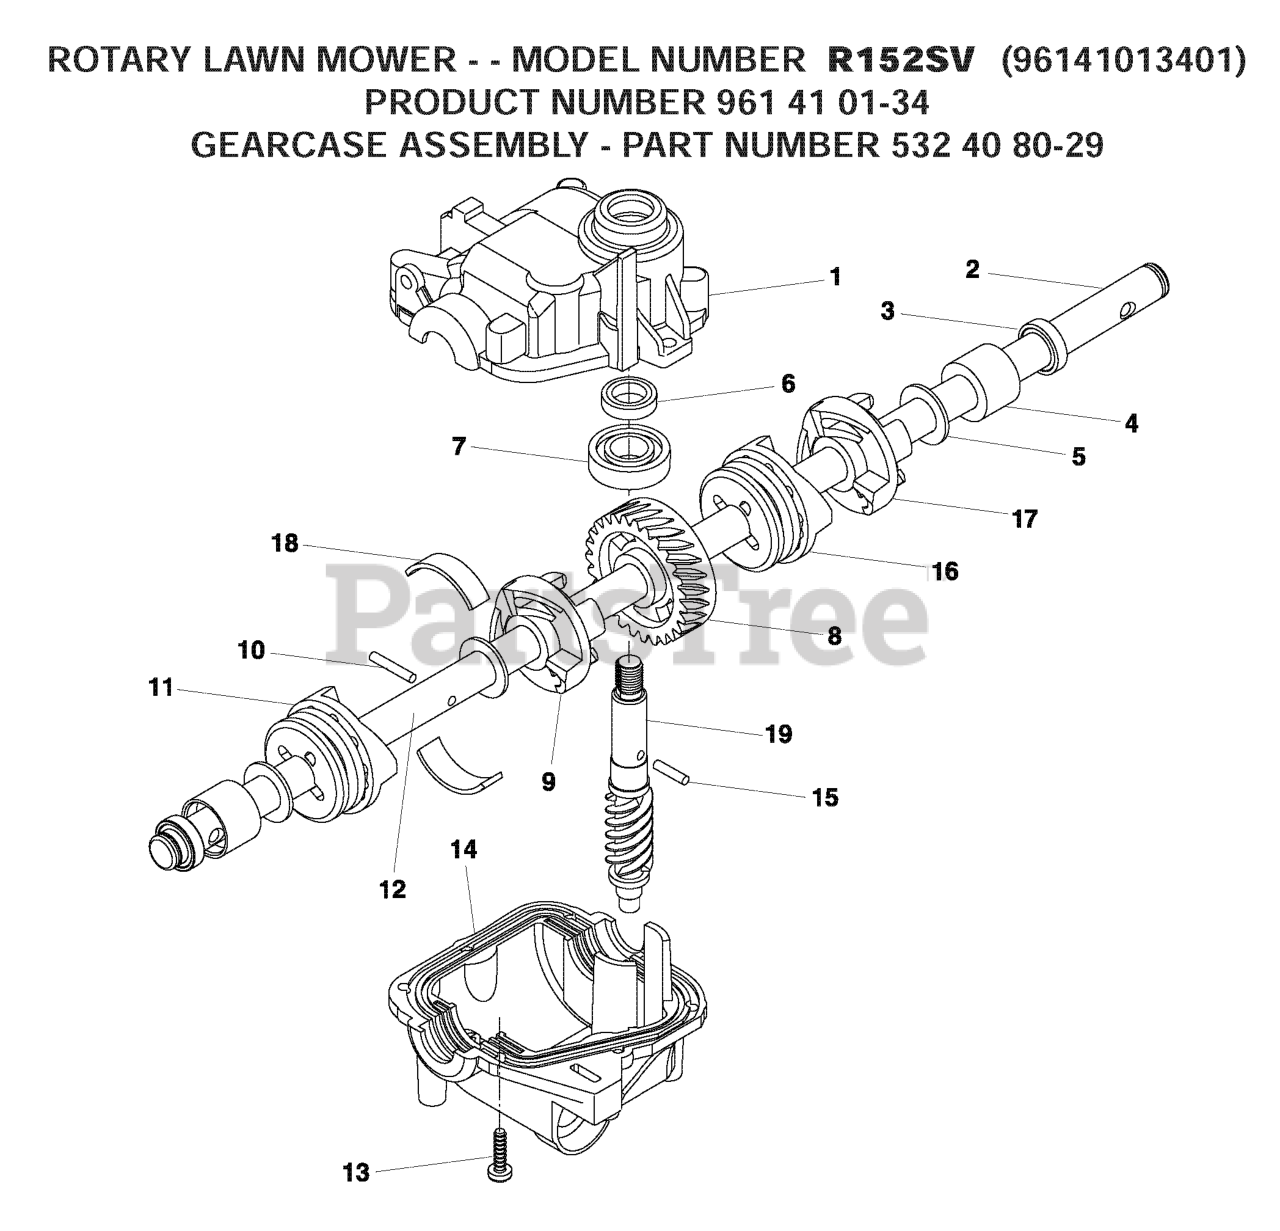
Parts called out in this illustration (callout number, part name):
1	CASE UPPER
3	SEAL.OUTPUT.SHAFT
6	SEAL INPUT SHAFT
8	GEAR 28 TEETH
9	DOG.FIXED.LH.32003
10	PIN 3.50.337 - 33733
11	DOG.MOVEABLE.LH.32005
14	CASE, LOWER
15	PIN 7 33732
16	DOG.FIXED.RH.32004
17	DOG.MOVEABLE.RH.32006
18	SPRING LEAF
